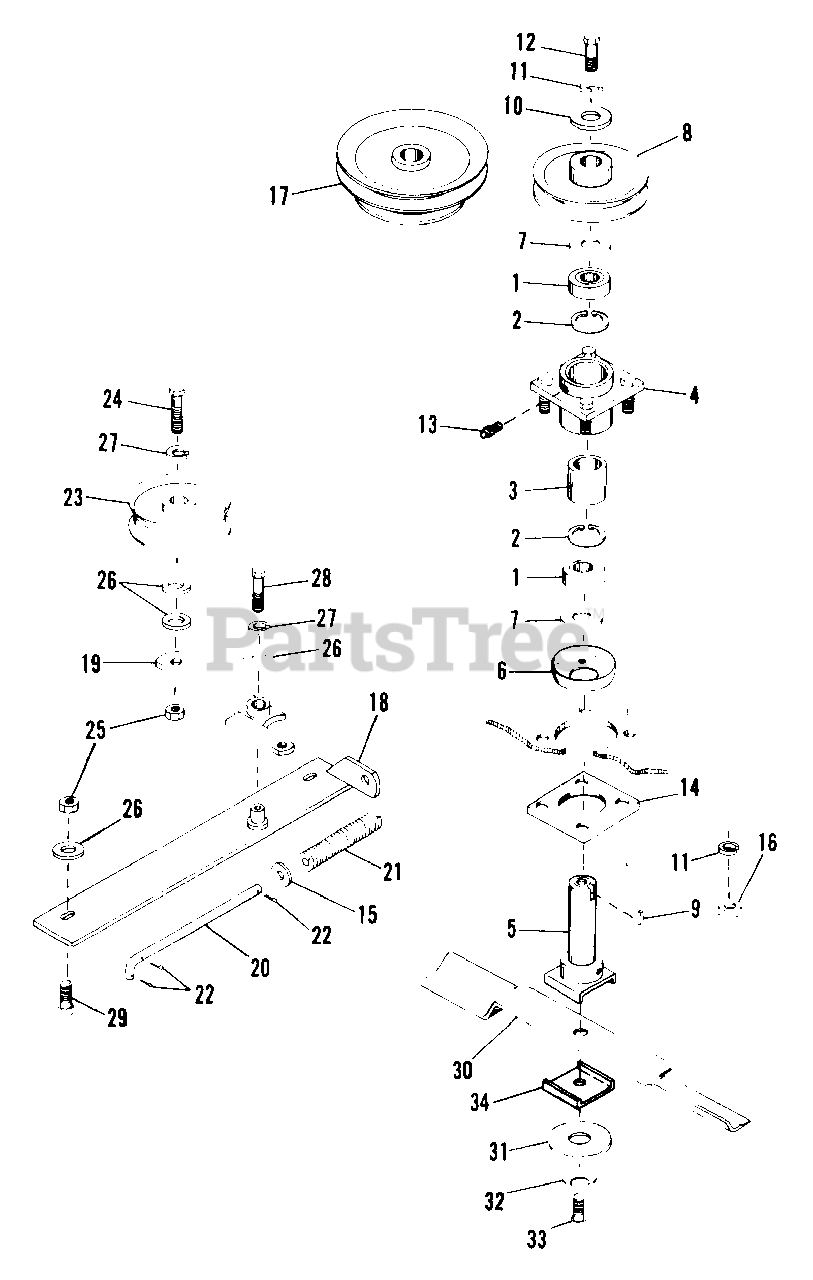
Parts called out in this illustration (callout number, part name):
1	BEARING, BALL
2	RING, 2.280 INT RET
3	SPACER
4	HOUSING, SPINDLE
5	SHAFT, SPINDLE
6	CUP, HUB BEARING
7	WASHER
8	PULLEY, OUTER
9	KEY, 1/4 x 1 SQ PARALLEL
11	WASHER, 1/2 LOCK
12	BOLT, 1/2-NF x 1-1/4 TYPE 5
13	FITTING, 1/4 LUB
13	FITTING, 1/8 PTF x/SHORT w/VENT LUB
14	PLATE, SPINDLE
15	WASHER, .531 x 1.062 x 074
16	NUT, 1/2 TYPE 5
17	PULLEY, CENTER
22	PIN, 1/8 x 1-1/4 COT
23	PULLEY, IDLER
24	BOLT, 3/8 x 1-3/4 TYPE 5
25	NUT, 3/8 CAD P/T LOCK TYPE 5
26	WASHER, .438 x 1.000 x .064
27	WASHER, 3/8 LOCK
28	BOLT, 3/8 x 3/4 TYPE 5
29	BOLT, 3/8 x 1 TYPE 5
30	BLADE
31	WASHER
32	WASHER, SPECIAL
33	BOLT, 1/2-NF x 1-1/2 TYPE 5
34	RETAINER, BLADE
